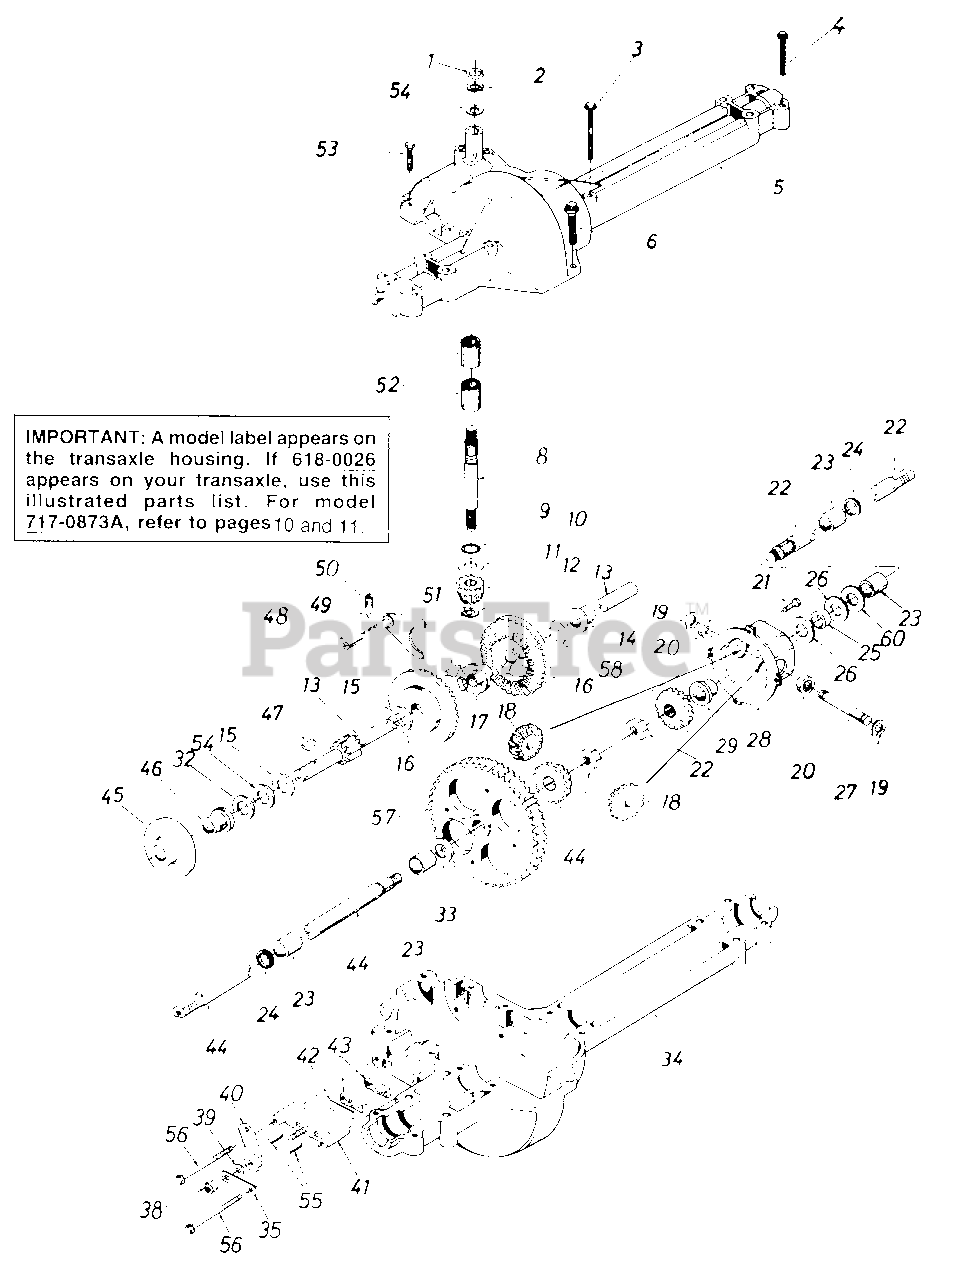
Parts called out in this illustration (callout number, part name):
2	Retaining-Ring
3	Hex Bolt 1/4-20 x 1.75" Lg.
4	Hex Tap Scr. 1/4-20 x 1.25" Lg.
5	Upper Housing
6	Hex TT-Tap Scr. 1/4-20 x .75" Lg.
9	Square Seal 5/8" I.D.
10	Thrust Washer 5/8" I.D. x 1.25" O.D.
11	Pinion Input 14T
12	Retaining Ring
14	Flange Brg. 5/8" I.D. x 3/4" Lg.
15	Fl-Wash. 5/8" I.D. x 1.25"
16	Bevel Gear 42T
17	Clutch Collar
18	Miter Gear 15T
19	Snap Ring
20	Thrust Bearing
21	Pan Head Scr. 1/4-20 x .50" Lg. w/Patch
22	Axle R.H. Ass'y.
23	Sleeve Bearing 3/4" I.D. x 1.0" Lg.
24	Oil Seal 3/4" I.D.
26	Fl-Wash. .760" I.D. x 1.5n O.D.
28	Differential Cam Ass'y.
32	Washer
33	Fl-Wash. .760" I.D. x 1.5n O.D.
34	Lower Housing
35	Anti-Rotation Brkt.
38	Hex Nut 5/16-24 Thd.
39	Fl-Wash. .344" I.D. x .875n O.D.
40	Actuating Arm
41	Brake Yoke
42	Puck Plate
43	Brake Puck
44	Axle L.H. Ass'y.
46	Flange Bearing 5/8" I.D. x 15/16n Lg.
47	Woodruff Key 3/16 x 5/8 HT
48	Shift Fork Ass'y.
49	Ball Detent .250" Dia.
50	Spring Detent
51	#9 Hi-Pro Key 3/16" x 3/4" Dia. HT
52	Needle Brg. 5/8" l.D. x 1/2" Lg.
53	Hex Bolt 1/4-20 x 1.00" Lg
54	Fl-Wash. 5/8" l.D. x 1" O.D. x .020 Thk.
55	Actuating Pin 5/16" Dia.
56	Hex Wash Hd. Self-Tap Scr. 1/4-20 Thd.
57	Differential Gear 72T Ass'y. w/Bearing
58	Fl-Wash. 5/8" l.D. x ln O.D. x .020 Thk.
60	Washer
